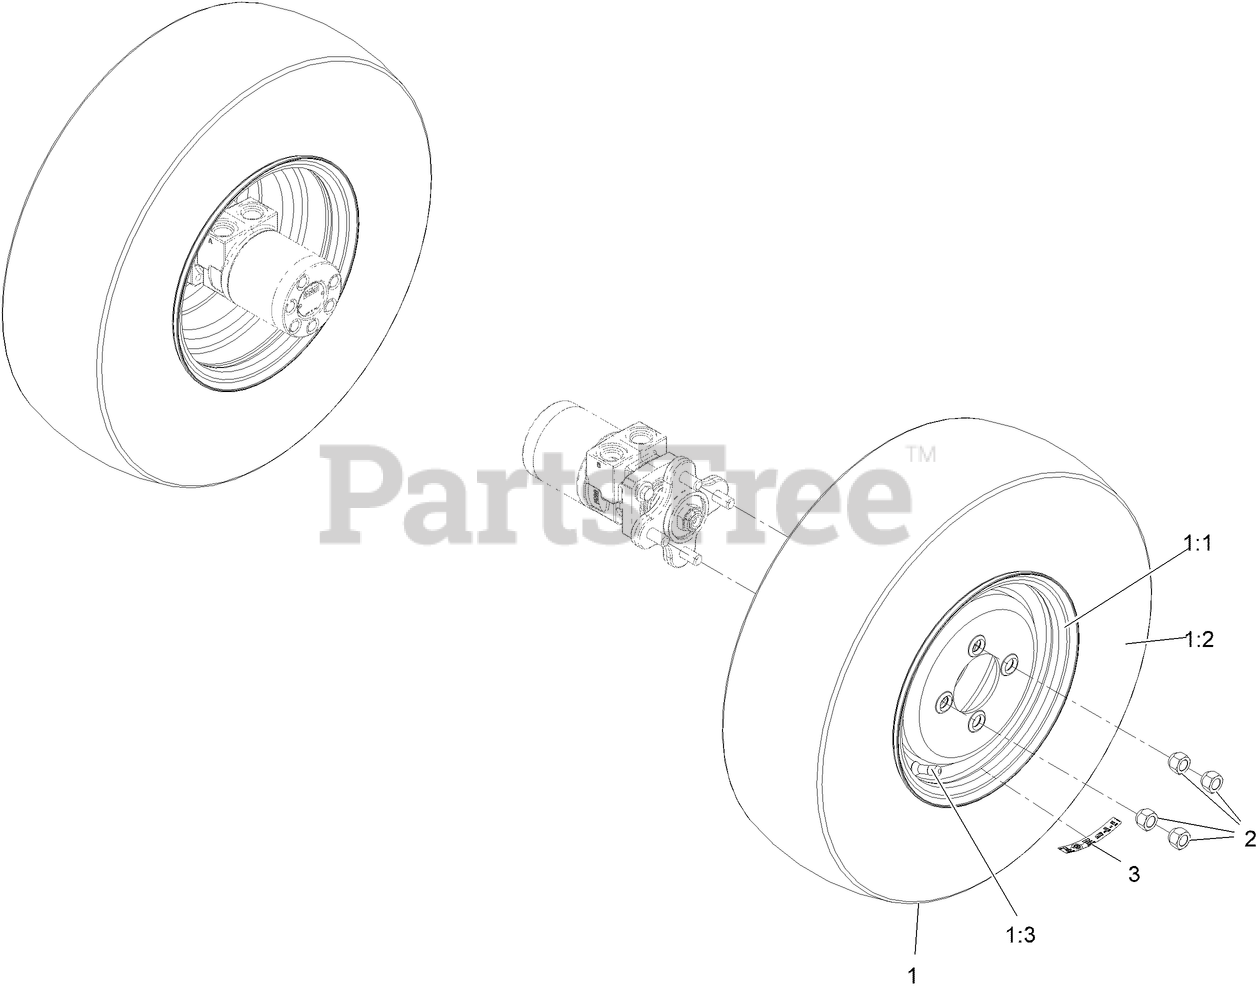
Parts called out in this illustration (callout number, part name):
1	ASM-WHL TIRE
1:1	WHEEL 10 X 5.5 WHT
1:2	TIRE 21X7.00-10
1:3	Stem-Valve
2	NUT-LUG
3	DECAL-TORQUE WHEEL LUG-HU
